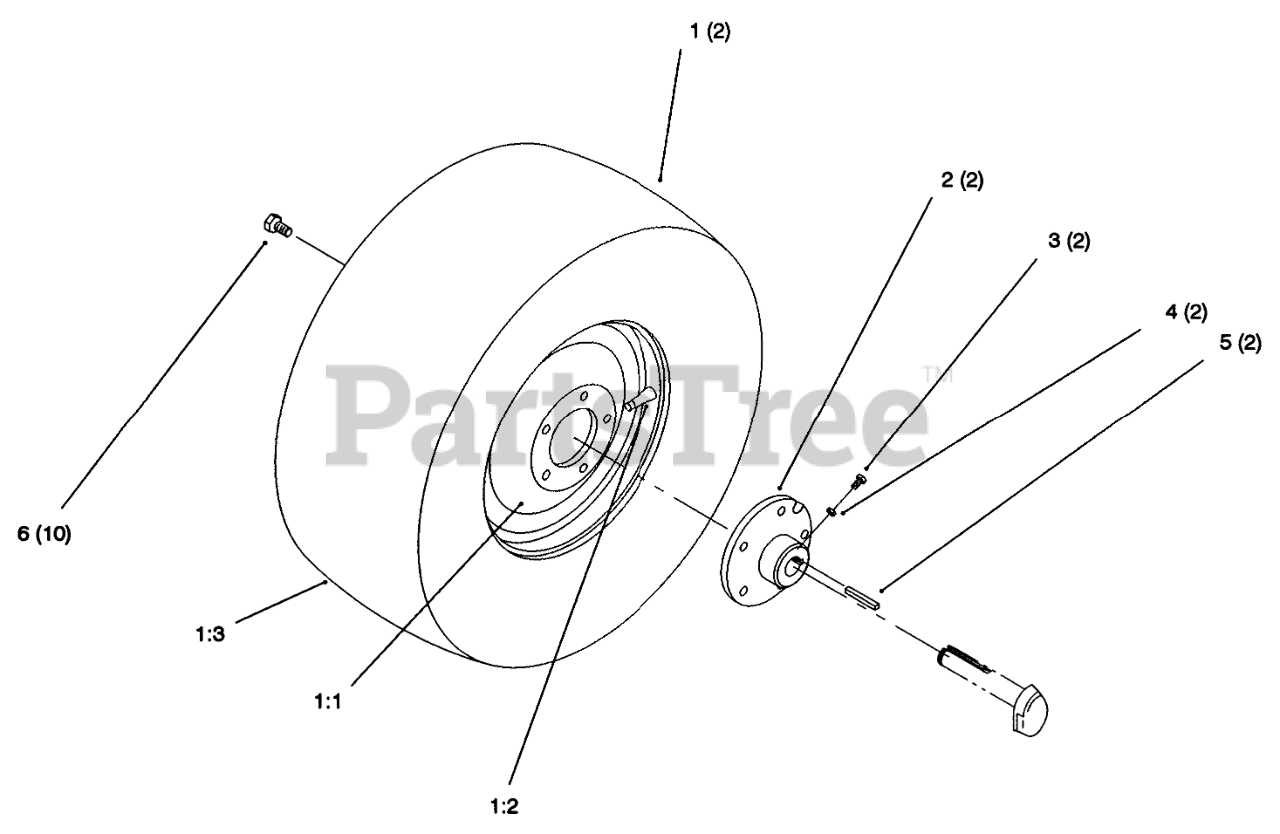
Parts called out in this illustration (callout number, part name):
1	Wheel & Tire ASM Rear
1:1	WHEEL
1:2	VALVE
1:3	TIRE 23 X 10.50-12
2	Hub-Wheel
3	SCREW-SET, SQH
4	NUT-JAM
5	KEY-SQUARE
6	BOLT-LUG
7	12"-HUB CAP LOGO
